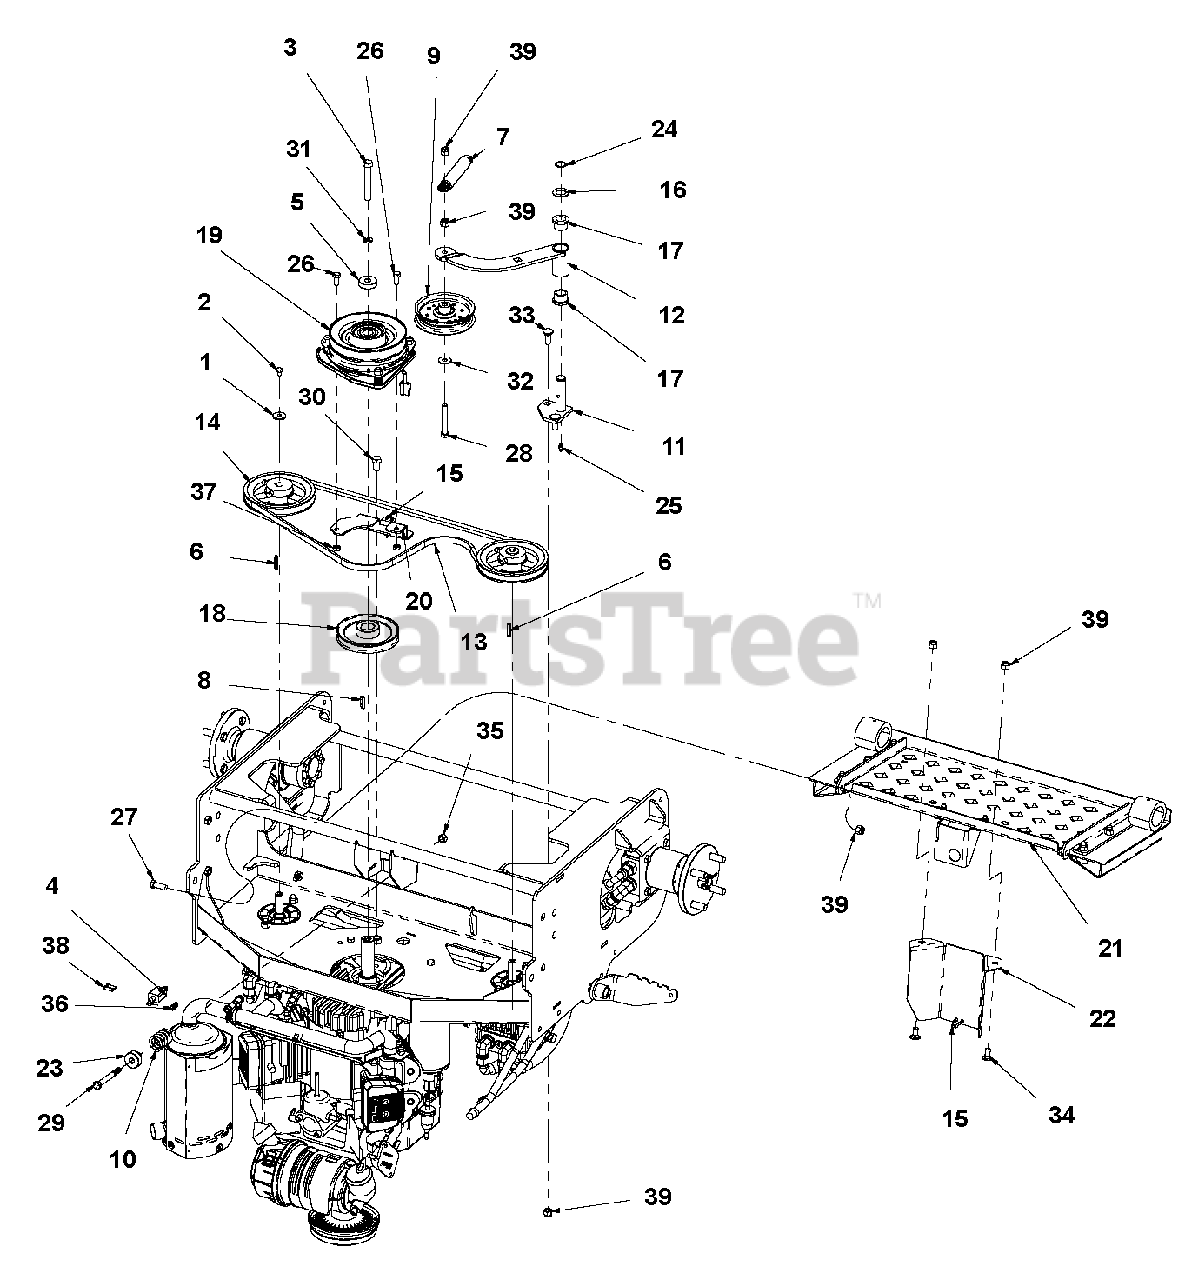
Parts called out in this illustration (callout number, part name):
1	WSHR-LK .250X.077 HVY YWZC
2	BOLT, M6X1.00X10 HEX 8.8 Y
3	BLT-HEX .44-20X2.25 G5 YZ EP80
4	SWITCH
5	SPACER, PTO CLUTCH
6	KEY, .250 X .250 X .995 TPR
7	SPRING, EXT .900X.135X4.50 Y
8	KEY, .250 X .250 X .995 TPR
9	ASM, IDLER 4"
10	SPRING
11	PLATE, IDLER MOUNT
12	ARM, IDLER WELDMENT
13	V-BELT
14	ASSY, PUMP PULLEY W/SET SCREW
15	TIE WRAP, BLACK LG 7.31
16	WSHR-FL-STL .750X1.250X.048 YZ
17	BRG, FLG .750X1.00X.750 BRNZ
18	SHEAVE, ENGINE 4.75X1.125
19	CLUTCH, OGURA GT1A-AR03
20	PLATE, CLUTCH DOG
21	ASSEMBLY, FOOT PLATE
22	SCREW, CYLINDER, D912 M 4X 5
23	WASHER, SPRING Y
24	SNAP RING, .750 X .042 EXT
25	GREASE ZERK, 1/4-28 STR .69 LG
26	@BLT-HEX .31-18X.75 GR5 YWZC
27	@BLT-HEX .38-16X1.00 GR5 YWZC
28	@BLT-HEX .38-16X2.50 GR5 YWZC
29	@BLT-HEX .38-16X3.25 GR5 YWZC
30	@BLT-HEX .44-14X.75 GR5 YWZC
31	WASHER, .438 MED SPRG LOCK Y
32	@WSHR-FL-STL.438X1.00X.083 YWZ
33	@BLT-RDHDSQNK .38-16X1.00 G5YZ
34	@BLT-RDHDSQNK .38-16X.75 G5YZ
35	@NUT-HEX .31-18 YWZC
36	@NUT-LK-NYL 10-24 W/INSRT YWZC
37	@NUT-LK-NYL .312-18 YWZC
38	SCR-MCH 10-24X.62 P/HD
39	@NUT-LK-NYL .38-16 YWZC
